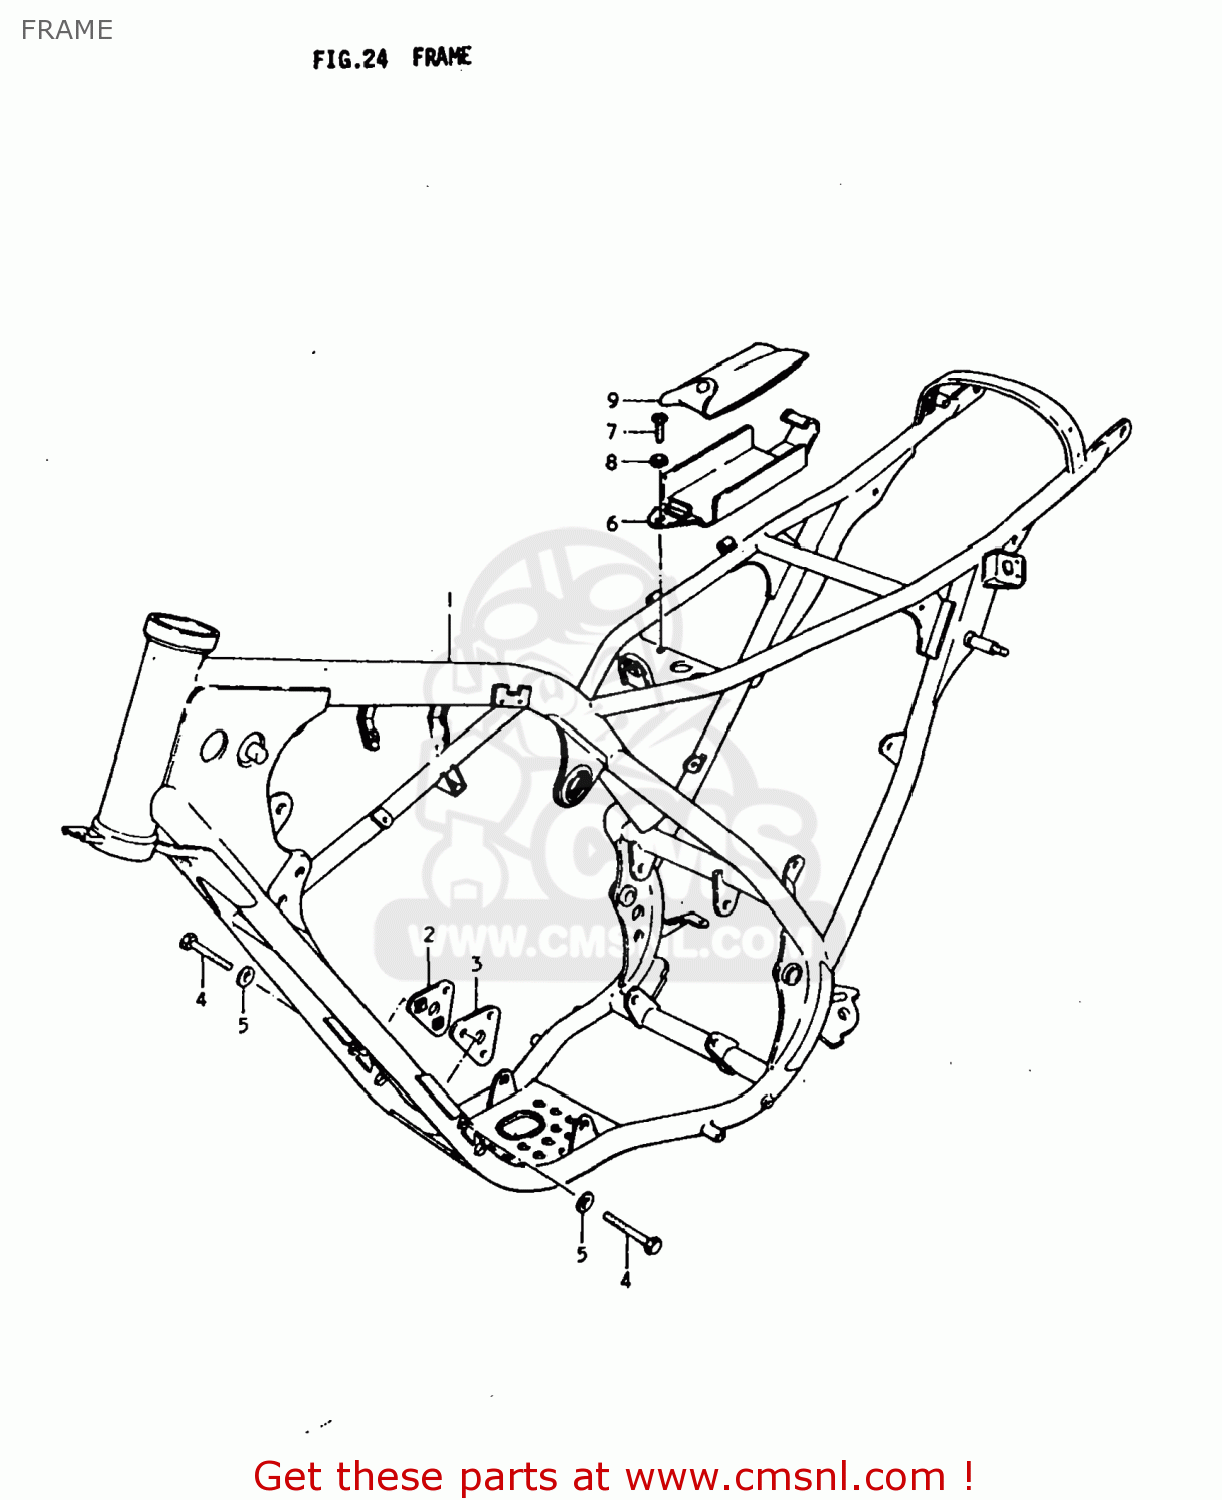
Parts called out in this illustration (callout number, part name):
1	FRAME
2	PLATE,ENGINE MOUNTING
3	PLATE,ENG MTG,L
4	BOLT 8X55
5	WASHER
6	HOLDER,TOOL
7	SCREW
8	WASHER
9	TOOL ASSY
